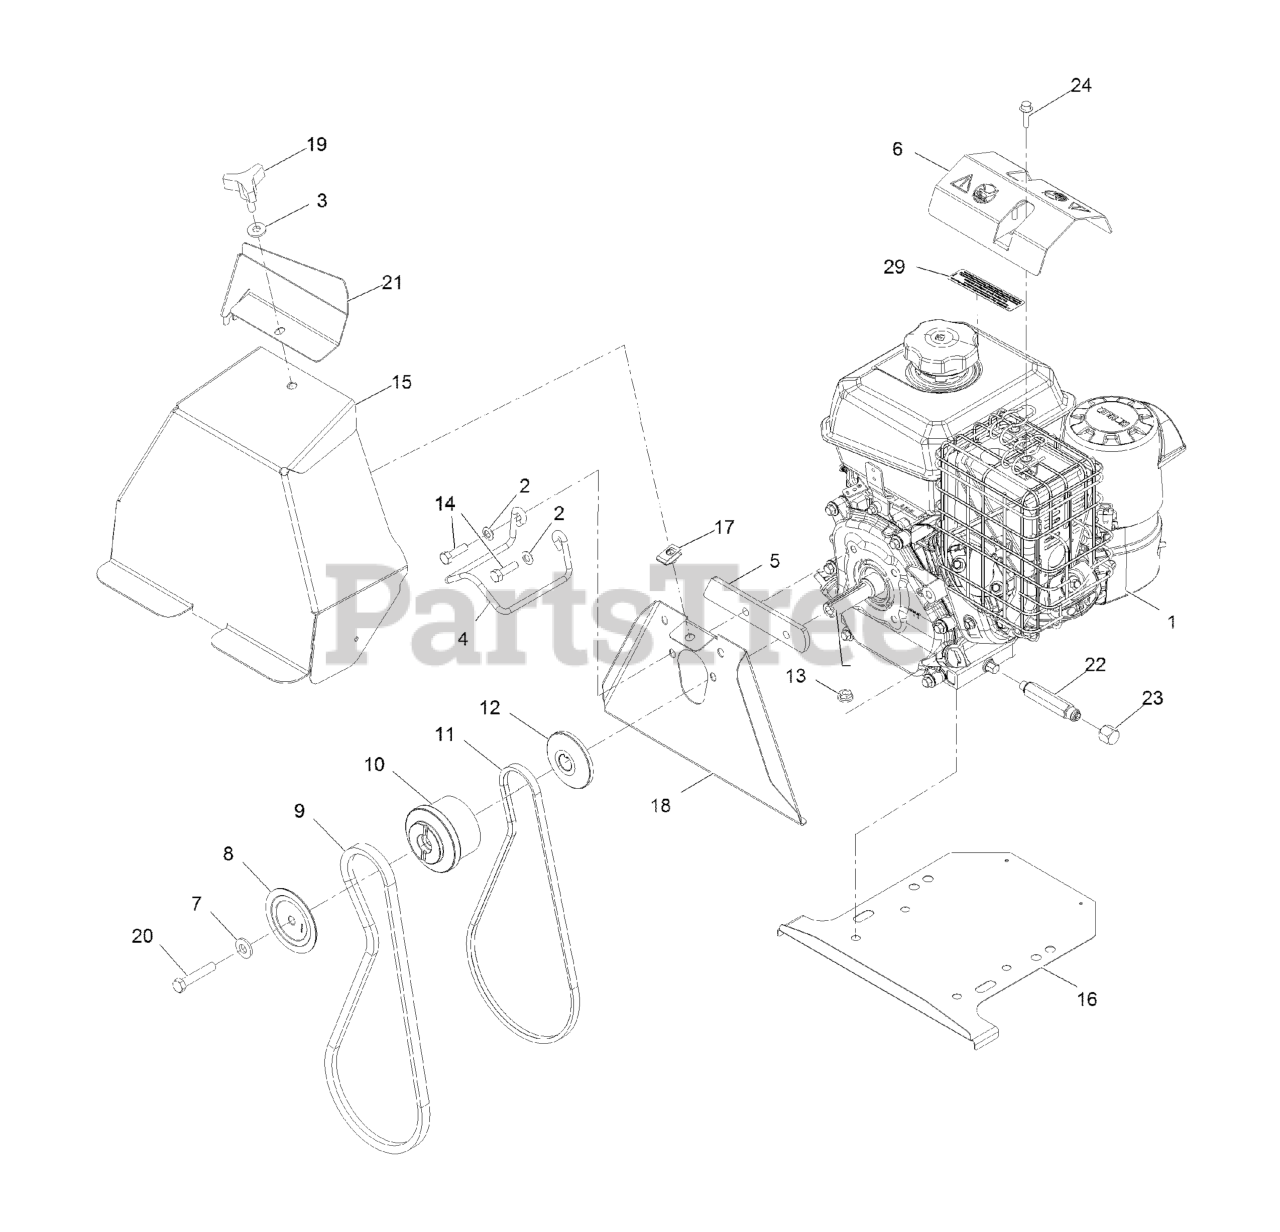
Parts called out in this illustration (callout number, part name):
2	WASHER-BELLEVILLE
3	WASHER-SPRING
4	GUIDE-BELT
5	SPACER-COVER, BELT
6	DEFLECTOR-DEBRIS, MUFFLER
7	WASHER-BELLEVILLE
8	SHEAVE-HALF, IMPELLER
9	BELT-BLOWER
10	PULLEY-ENGINE, CENTER
11	V BELT-TRACTION
12	SHEAVE-HALF, TRACTION
14	SCREW-HH
15	COVER - BELT
16	SHIELD-DRIVE
18	COVER-BELT, BACK
20	SCREW-HH
21	SHIELD-ICE, KC CH270
22	ADAPTER
24	SCREW-HHF
29	DECAL-ARRESTOR, SPARK
